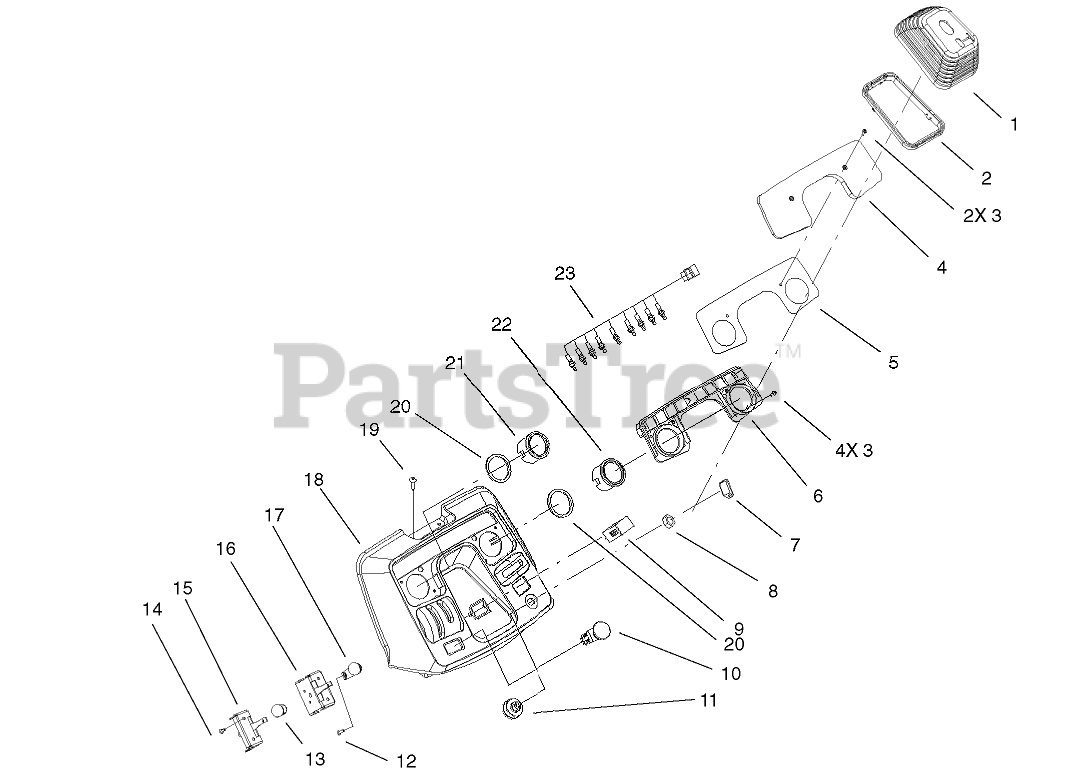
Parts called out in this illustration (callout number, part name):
1	BOOT-STEERING
2	RETAINER-BOOT
3	SCREW-PPH
4	LENS-DASH
5	DECAL-LENS, DASH
6	HOUSING-LIGHT, DASH
7	KEY-IGNITION
9	HOURMETER
10	SWITCH-PTO
11	SWITCH-IGNITION
12	SCREW-PPHTF
13	KNOB-THROTTLE
15	THROTTLE CONTROL ASM
16	CHOKE CONTROL ASM
17	KNOB-CHOKE
19	SCREW-HH
20	GASKET-FOAM
21	GAUGE-OIL TEMPERATURE
22	GAUGE-FUEL
23	HARNESS-LIGHT
